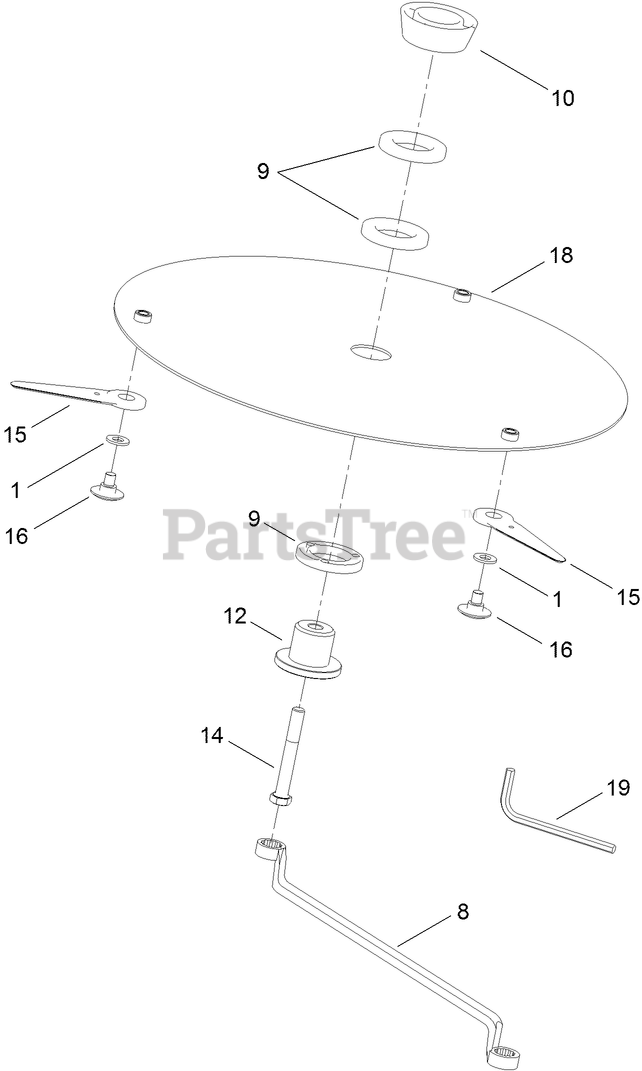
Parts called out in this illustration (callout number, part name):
1	WASHER-PLAIN
8	SPANNER
9	SPACER-BLADE, ALUMINIUM
10	SPACER-DISTANCE
12	RETAINER-BLADE
14	SCREW-SET
15	BLADE PLASTIC
16	BOLT SHOULDER SPECIAL
18	21" TRIM DISC
19	WRENCH-HEX
